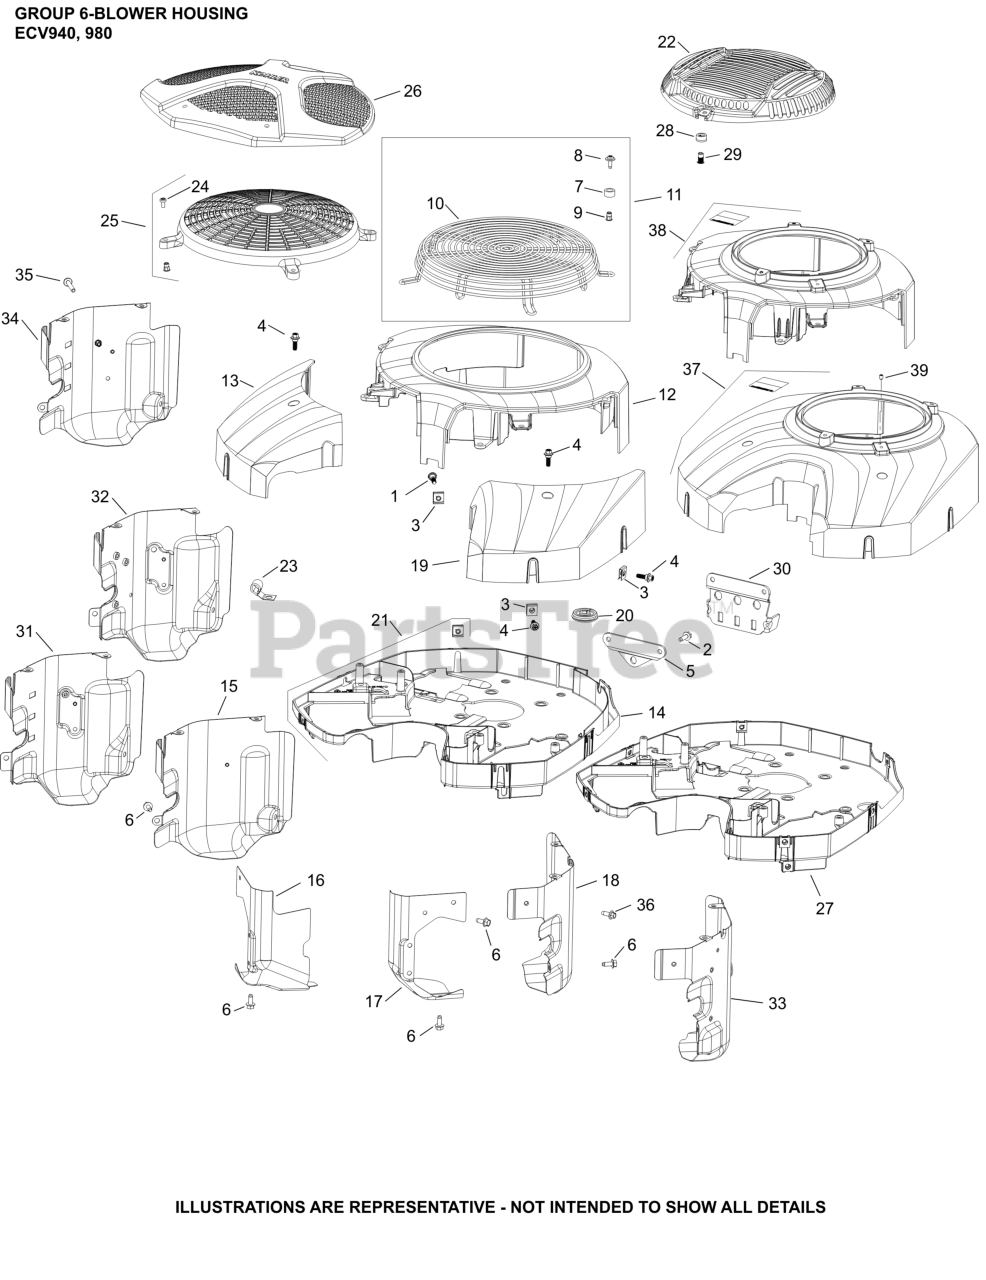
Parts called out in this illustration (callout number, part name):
1	SCREW, SHD THD FRM M6X1X26
2	SCREW, THREAD FORMING
3	CLIP, BAFFLE MOUNTING
4	SCREW, SHD THD FRM
5	STRAP, LIFTING
6	SCREW, THREAD FORMING
8	SCREW, SEMS
13	SHROUD, #1 CYLINDER
16	BAFFLE, VALLEY #1 CYLINDER
17	BAFFLE, VALLEY #2 CYL-USE 62 063 40-S
18	BAFFLE, BARREL (#2 CYL)
19	SHROUD, #2 CYLINDER
20	CGROMMET, WIRING HARNESS
22	GUARD, GRASS SCREEN (METAL)
27	SHROUD AND CLIP ASSEMBLY
31	BAFFLE, BARREL (#1 CYL)
36	SCREW, THREAD FORMING
38	KIT, BLOWER HOUSING
39	SCREW, SKT SET #10-24X1/4"
